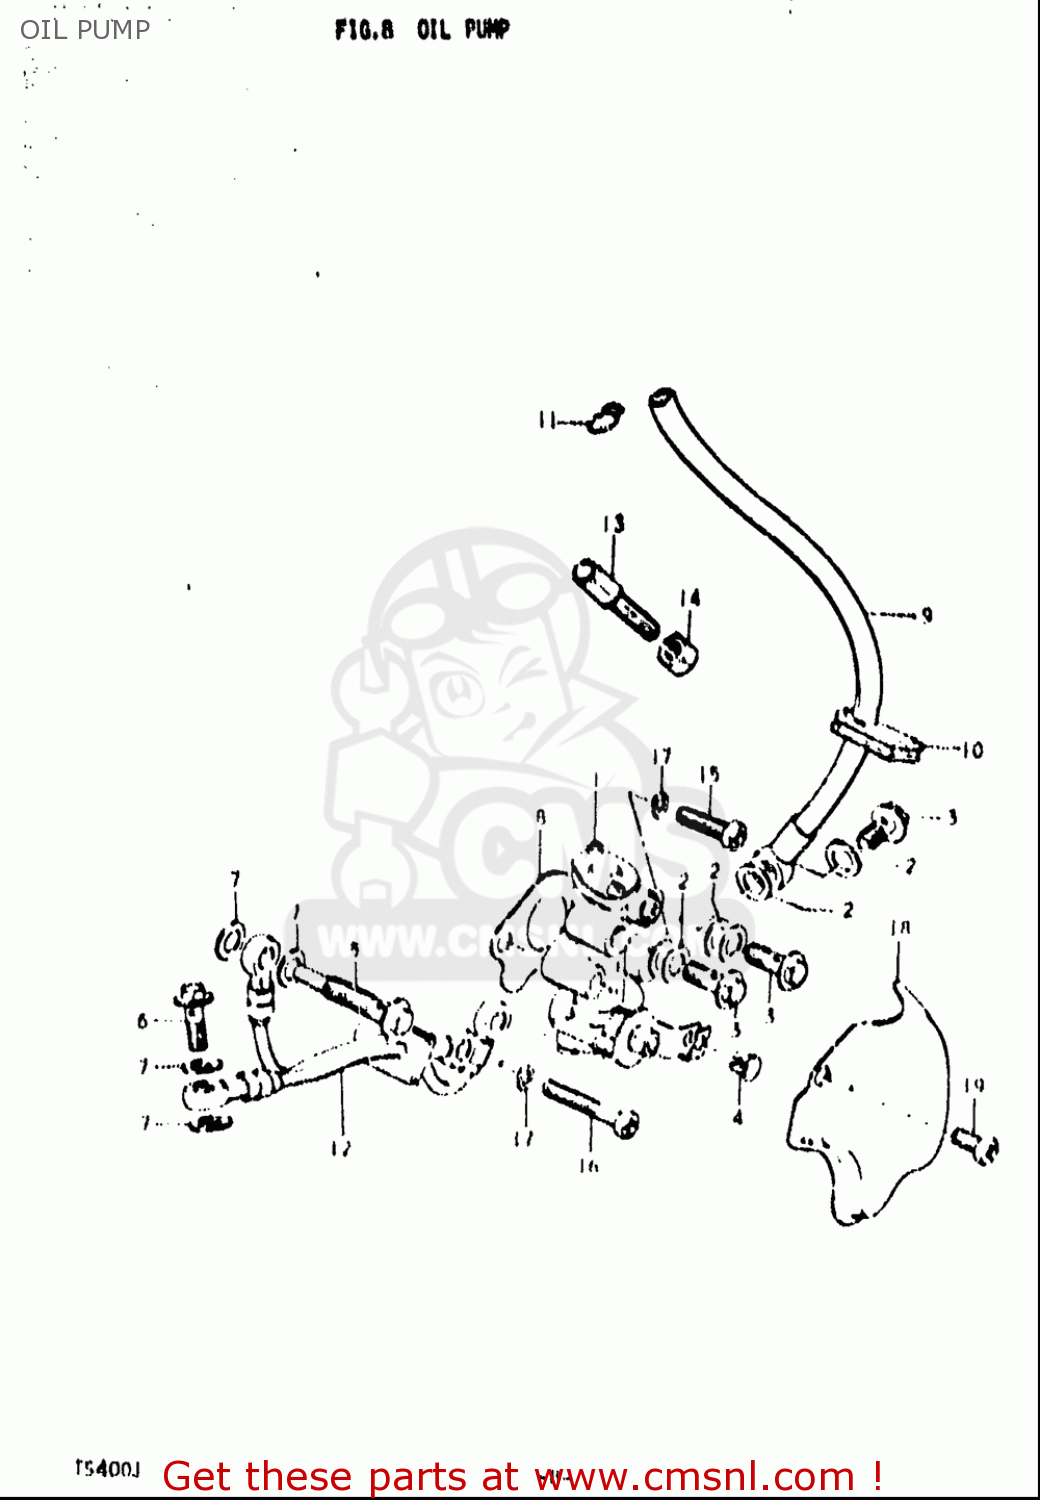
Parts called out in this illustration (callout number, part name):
2	GASKET(6.2X11X1).2 (NAS)
3	UNION BOLT
4	TERMINAL,CABLE
5	UNION
6	UNION BOLT
7	GASKET(6.2X11X1).2 (NAS)
8	GASKET,OIL PUMP (NAS)
10	GROMMET
11	CLIP
13	BOLT
14	NUT
15	SCREW
16	SCREW
17	WASHER,LOCK
19	SCREW
